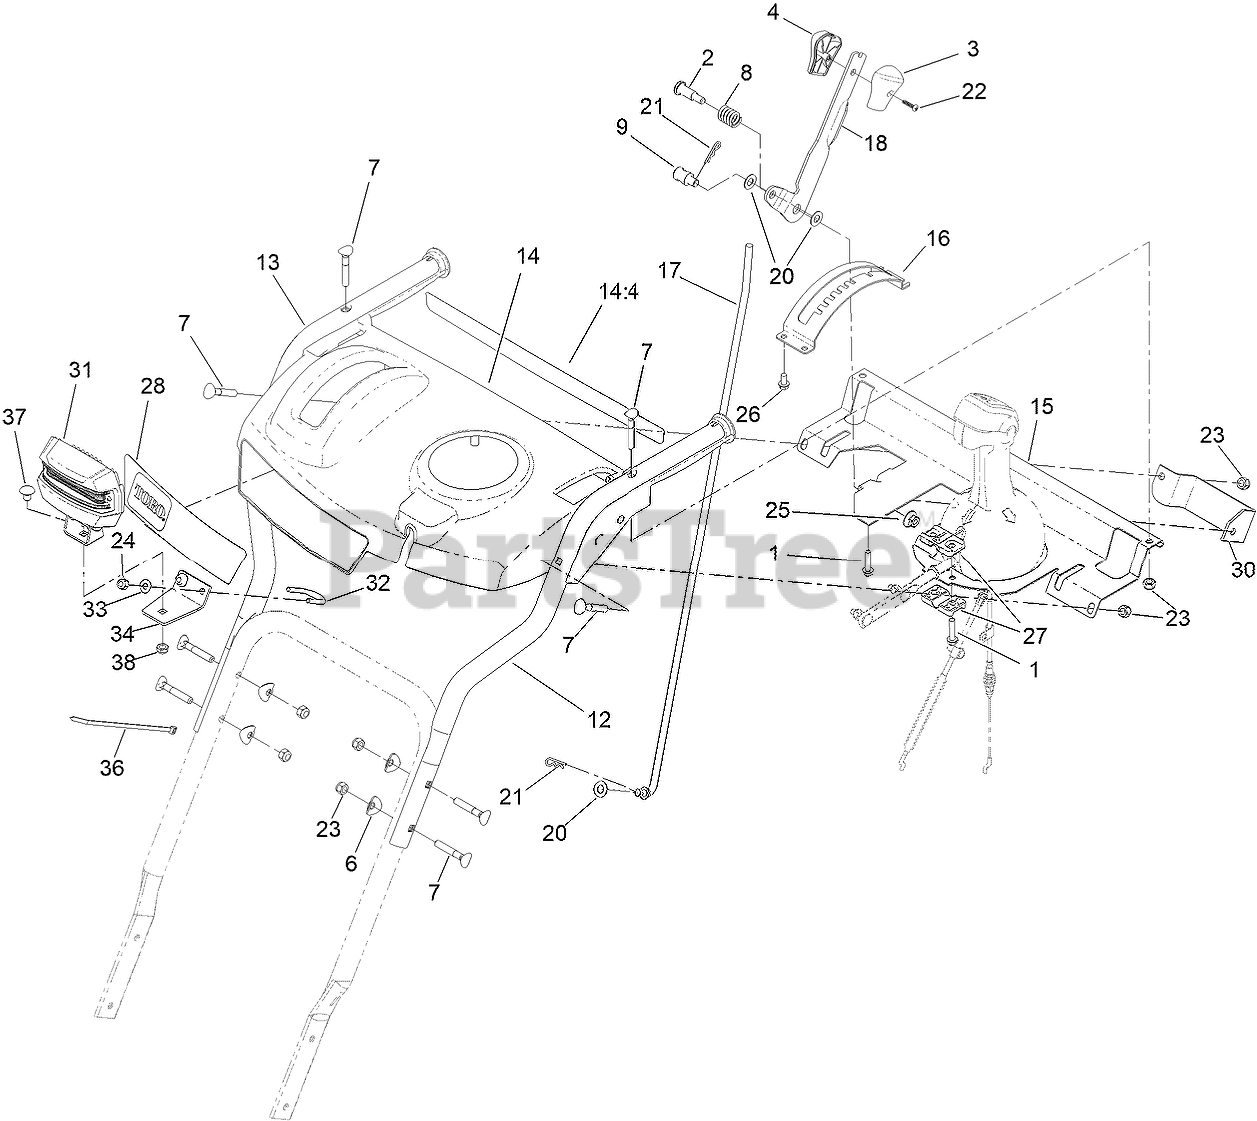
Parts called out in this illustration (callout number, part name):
1	SCREW-PLASTIC,HWH
2	SCREW-SHOULDER, HH
3	KNOB-SHIFT, LH
4	KNOB-SHIFT, RH
6	WASHER-CUP
7	SCREW-HANDLE
8	SPRING-COMPRESSION
9	TRUNNION-ROD
12	HANDLE-UPPER, LH
13	HANDLE-UPPER, RH
14	CONTROL PANEL ASM
14:4	DECAL-SAFETY
15	SUPPORT-PANEL, CONTROL
16	MOUNT-SELECTOR, SPEED
17	ROD-SELECTOR, GEAR
18	SELECTOR-SPEED
20	WASHER-THRUST
21	PIN-HAIR
22	SCREW-PPH
23	NUT-HEX
24	NUT-HEX
25	NUT-HF
26	SCREW-PLASTITE
27	SUPPORT-ROD
28	DECAL-CONSOLE
30	PLATE-SUPPORT, SHIFT
31	LED LIGHT ASM
32	CLAMP-LIGHT
33	WASHER-PLAIN
34	BRACKET-LIGHT
36	TIE-CABLE
37	BOLT-CARR
38	NUT-HEX
